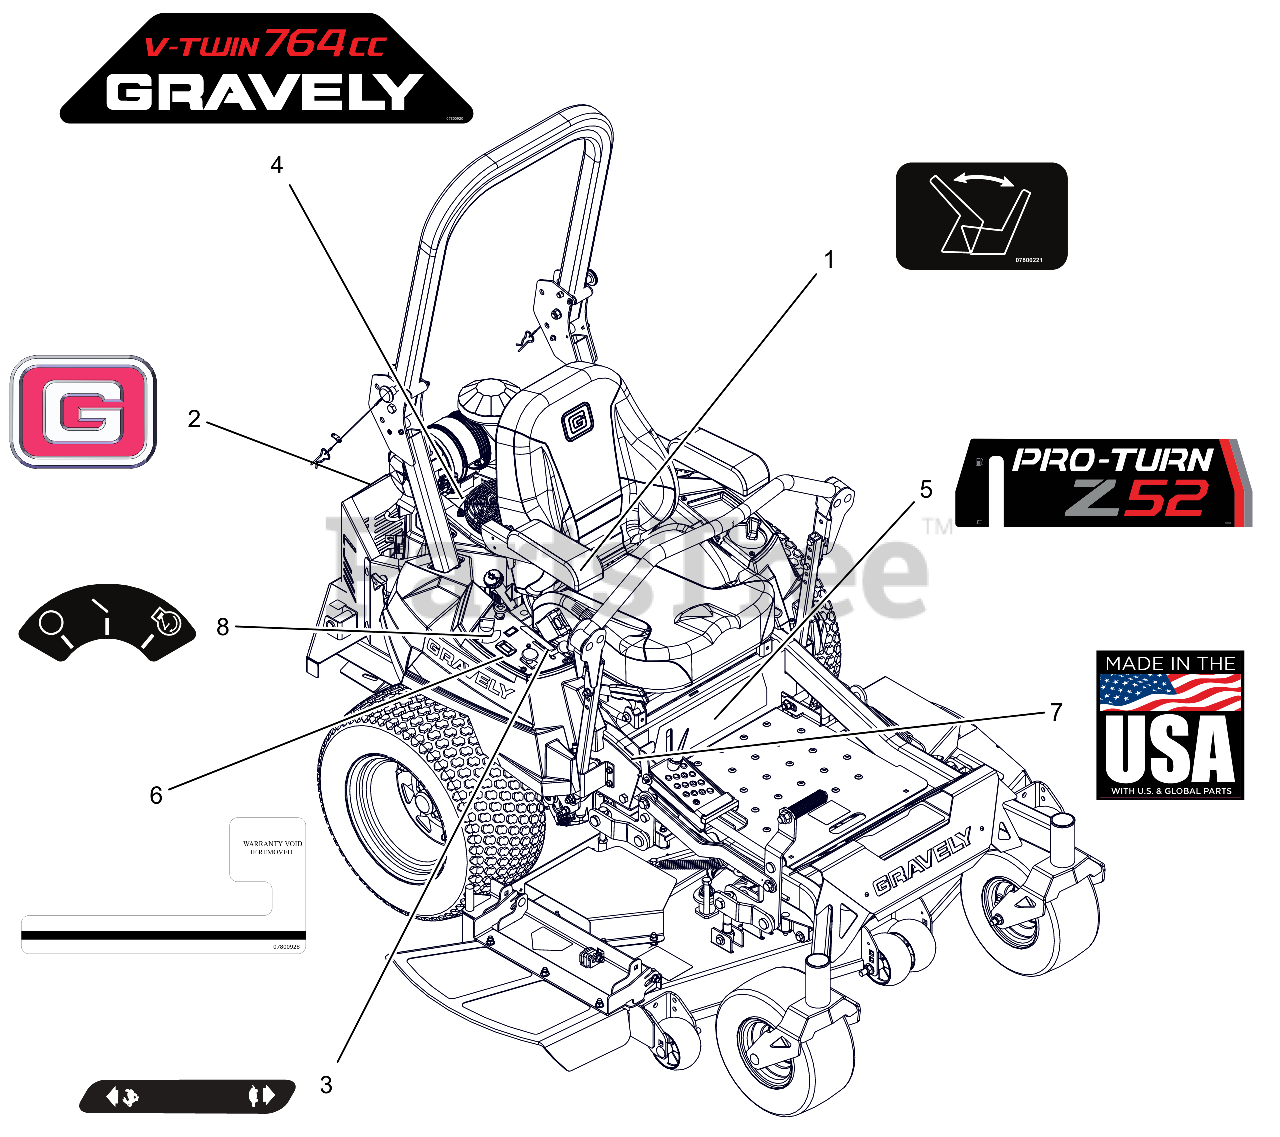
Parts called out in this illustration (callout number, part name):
1	DECAL - SEAT RELEASE
2	DECAL, GRAVELY BRAND
3	DECAL, DASH DECAL
4	DECAL,ENGINE - GRAVELY 764CC
5	DECAL, PRO-TURN Z52
6	DECAL,HOURMETER - SECURITY
7	DECAL, MADE IN USA
8	DECAL, KEYSWITCH
